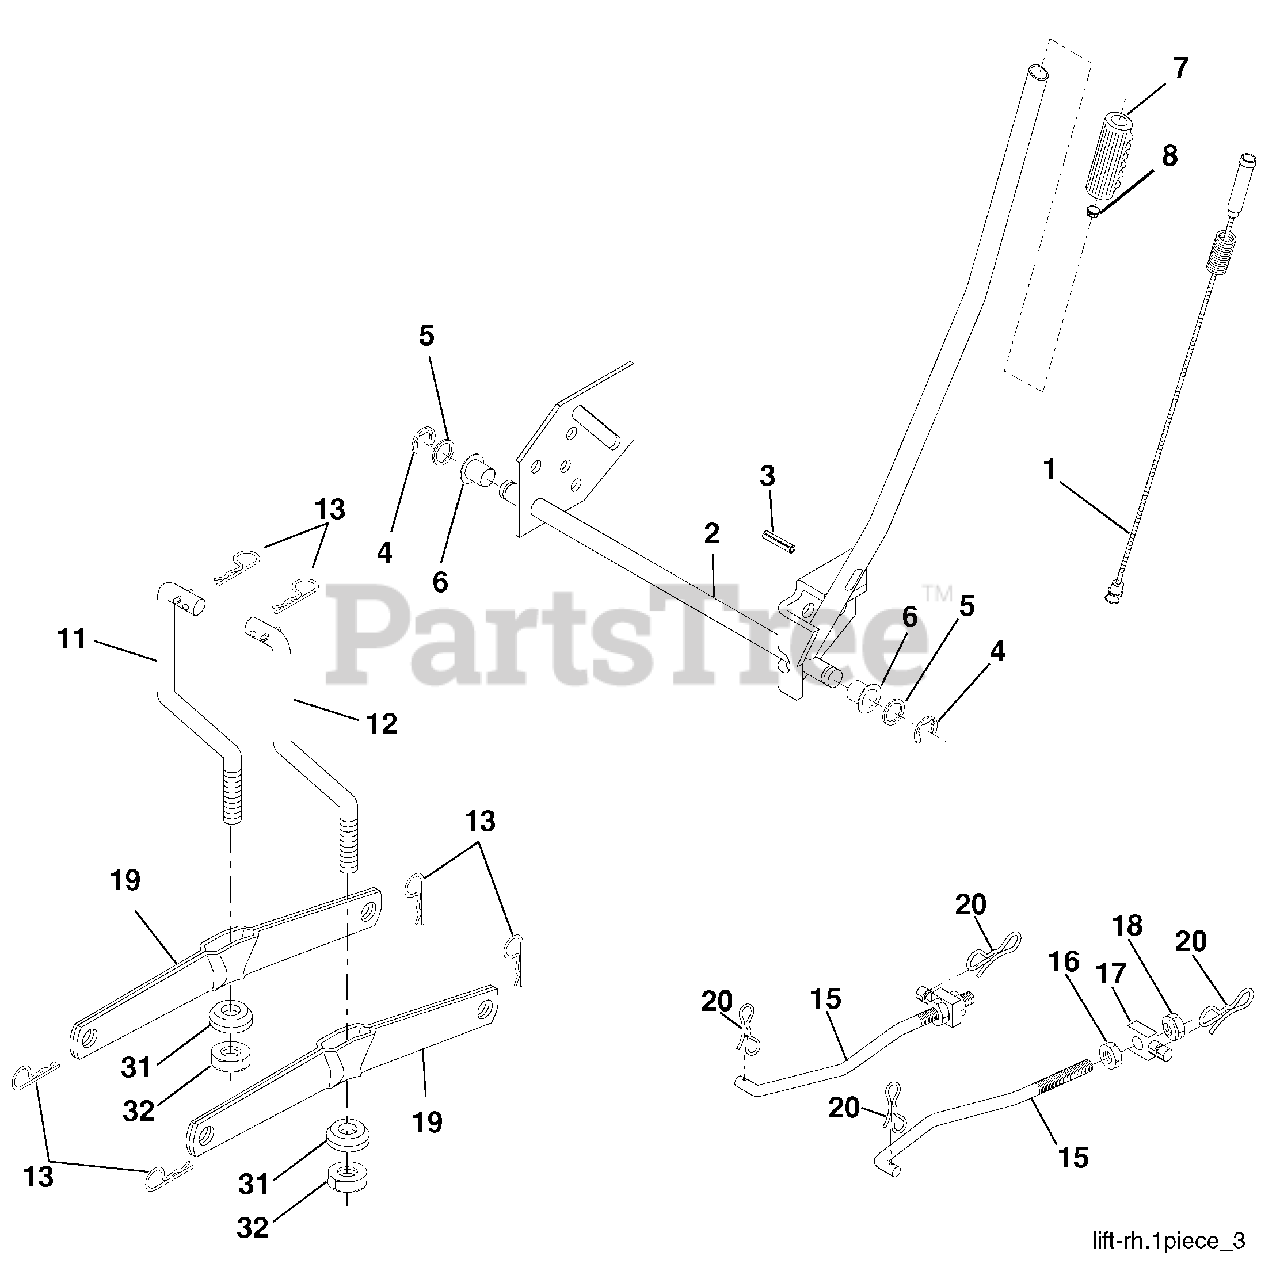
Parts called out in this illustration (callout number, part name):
1	Plunger Asm Lift Lever
2	Shaft Asm Lift RH
3	Pin Groove 1 500 Zinc
4	E Ring #5133-62
5	Washer 21/32 x 1 x 21 Ga.
6	Bearing Nylon Blk 629 Id
7	Grip Handle
8	Button Plunger Red
11	Link Lift LH Fixed Length
12	Link Lift RH Fixed Length
13	Retainer Spring
15	Link Front
16	Nut Jam Hex 1/2-13 unc
17	Trunnion
18	Nut Lock w/Wsh 1/2-13 unc
19	Arm Suspension Rear
20	Pin Cotter 7/16 Bow Tie Lock
31	Bearing Pvt Lift
32	Nut Crownlock 3/8-24
